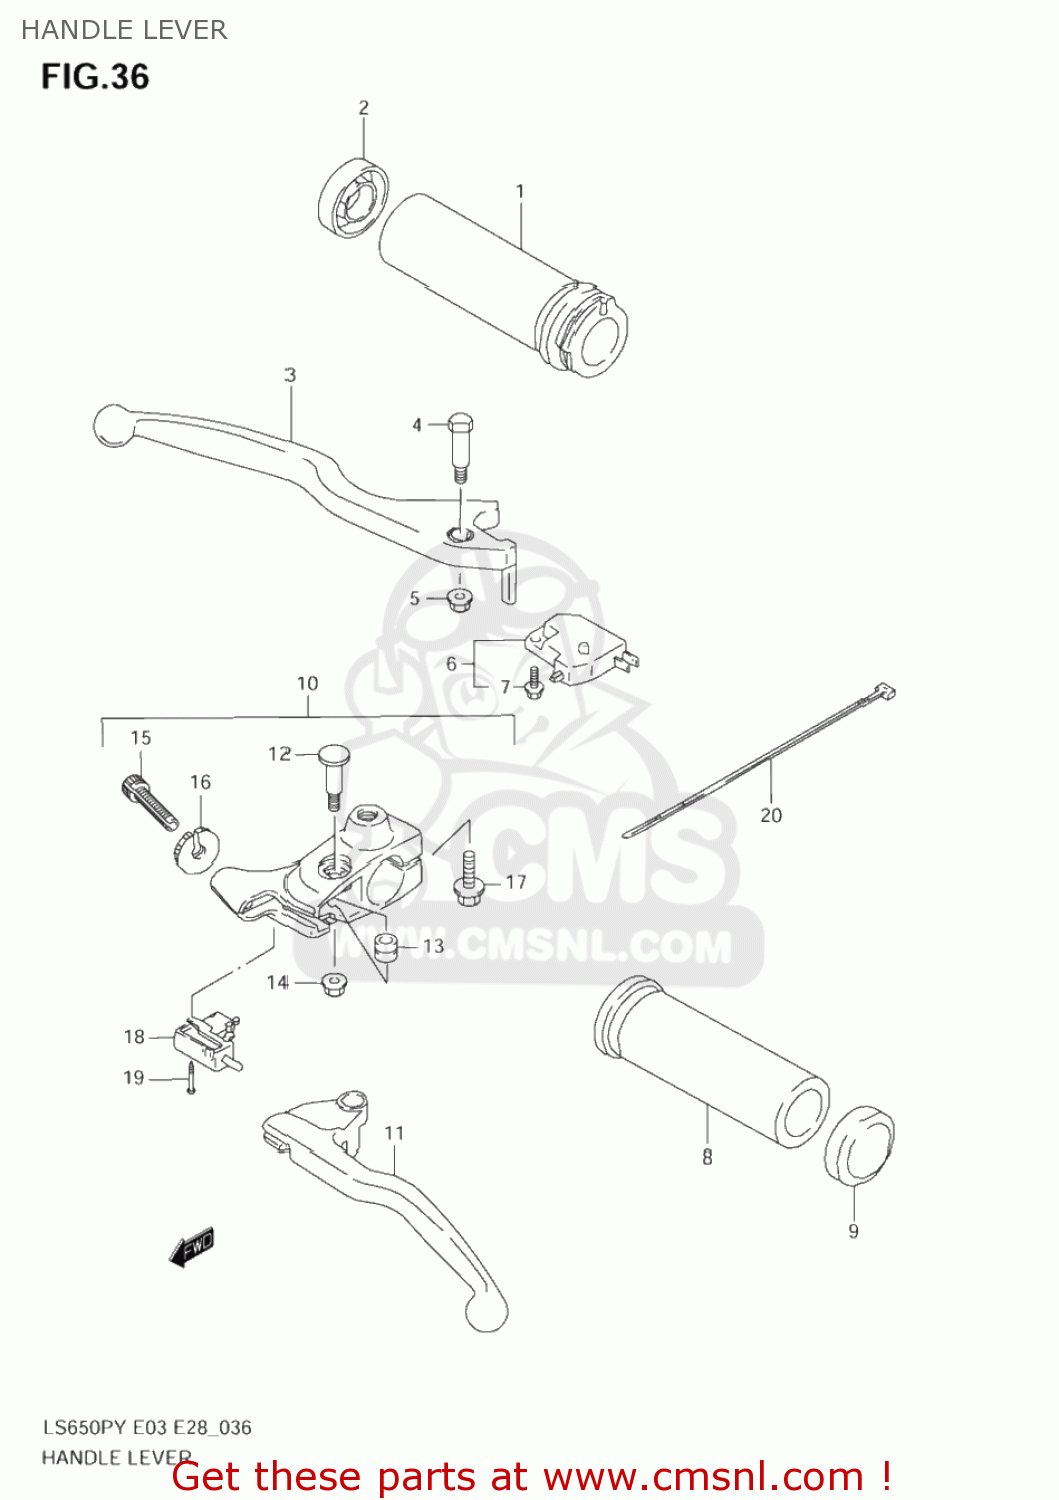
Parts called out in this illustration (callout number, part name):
1	GRIP,THROTTLE
2	CAP,GRIP END
3	LEVER,BRAKE
4	BOLT,LEVER SET
5	NUT 6MM
6	SWITCH ASSY,ST
7	SCREW
8	GRIP,L
9	CAP,GRIP END
10	LEVER ASSY,CLUTCH
11	LEVER,CLUTCH
12	BOLT,CLUTCH LEVER
13	SPACER,CLUTCH LEVER PIVOT
14	NUT 6MM
15	ADJUSTER,WIRE
16	NUT,LOCK
17	BOLT
18	SWITCH,CLUTCH
19	SCREW
20	CLAMP(L:250)
